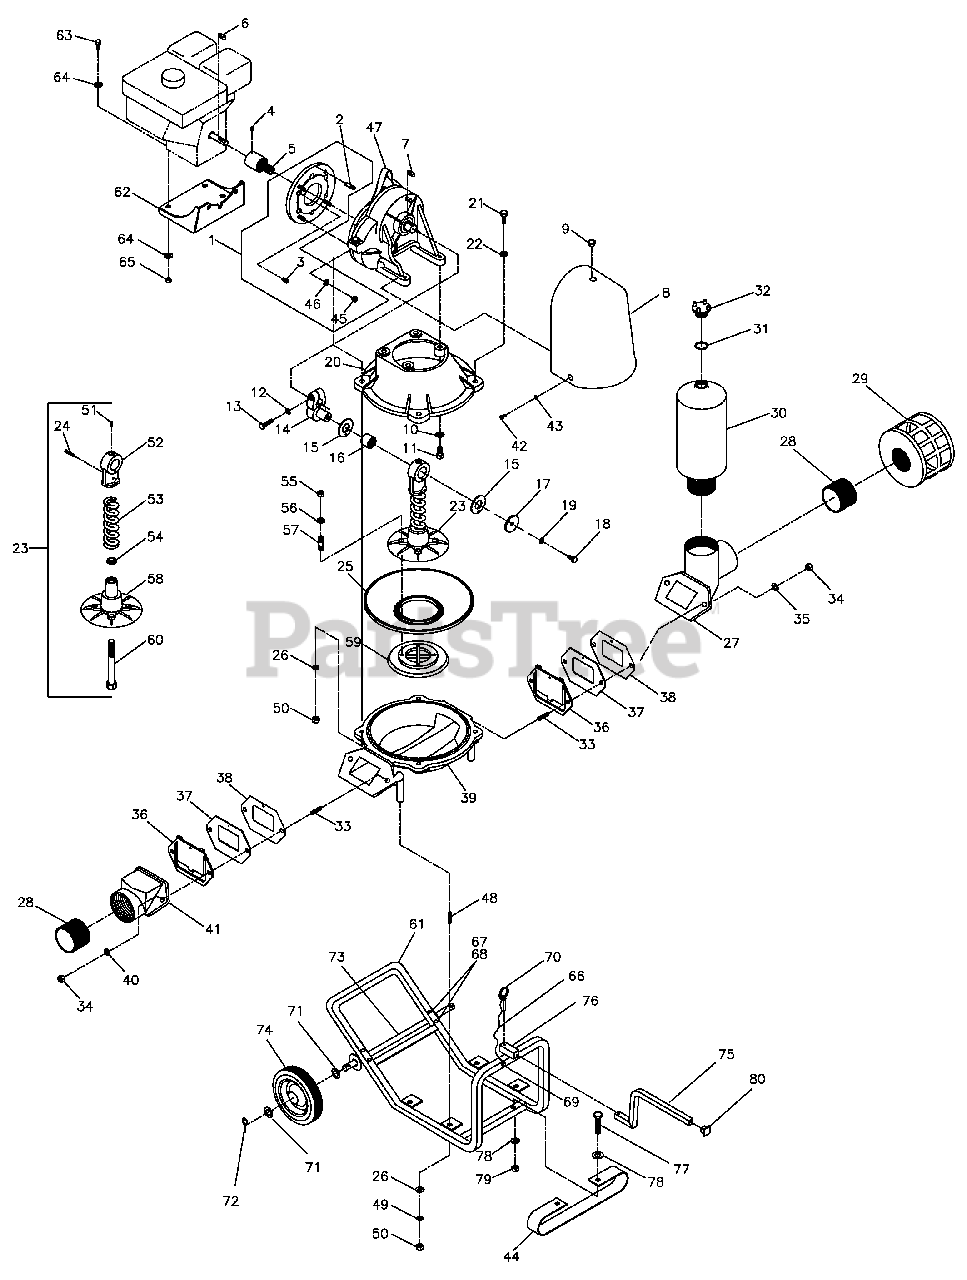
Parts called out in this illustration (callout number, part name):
1	ADAPTER, ENGINE
2	STUD (10X1.5X40) (W/NUT)
3	SCREW, ALLEN
3	SCREW, ALLEN (8X1.25X15)
4	SCREW SET (8MX1.25X10)
6	KEY STOCK (3/16X1)
8	COVER *R1* (RED)
9	PLUG, COVER (#35)
10	WASHER, PLAIN (12MM)
11	BOLT, HEX.
11	BOLT, HEX. (12X1.75X40)
12	WASHER, SPRING (10MM)
13	BOLT, HEX.
13	BOLT, HEX. (10X1.5X40)
14	CRANK (3" PUMP)
15	WASHER, FIBER
16	BEARING, CRANK
17	COVER, CONNECTING ROD BUSHING
18	BOLT, HEX.
19	WASHER, SPRING (10MM)
20	CASE, MOUNTING (UPPER) (ALUMINUM)
21	BOLT, HEX. (12X1.75X50)
22	WASHER, PLAIN (12MM)
23	ROD, CONNECTING
24	NIPPLE, GREASE
25	DIAPHRAGM, NEOPRENE
26	WASHER, FLAT (12MM)
26	WASHER, PLAIN (12MM)
27	PORT, SUCTION NPT (3")
28	NIPPLE (3")
29	STRAINER, TRASH SQ. HOLE (3")
30	CHAMBER, AIR NPT (3")
31	O-RING, AIR CHAMBER PLUG
32	PLUG, AIR CHAMBER (BRONZE)
33	STUD, FLANGE
34	NUT (12X1.75)
35	WASHER, FLAT (12MM)
35	WASHER, PLAIN (12MM)
36	CLAPPET, NEOPRENE
37	WEARPLATE, STAINLESS STEEL
38	GASKET, WEARPLATE PAPER
39	CASE (LOWER) (ALUMINUM)
40	WASHER, FLAT (12MM)
40	WASHER, PLAIN (12MM)
41	PORT, DISCHARGE (3")
42	BOLT, HEX. (8x1.25x15)
43	WASHER, FLAT (8MM)
43	WASHER, PLAIN (8MM)
44	SPRING, FRAME
45	NUT (10x1.5)
46	WASHER, SPRING (10MM)
47	TRANSMISSION, STRAIGHT TEETH (1:43)
48	STUD, PUMP CASE MOUNTING
49	WASHER, STAR (12MM)
50	NUT (12X1.75)
51	ROD END (UPPER)
53	SPRING, CONNECTING ROD
54	RING (INNER)
55	NUT (12X1.75)
56	WASHER, FLAT (12MM)
56	WASHER, PLAIN (12MM)
57	STUD (12X1.75-70)
58	ROD END (LOWER)
59	FLANGE, CONNECTING ROD
60	BOLT, SPECIAL
61	FRAME ASSY., WHEEL
62	BRACKET, ENGINE MOUNTING
63	BOLT, HEX. (5/16-18X1.5")
64	WASHER, FLAT (5/16" SAE)
65	LOCKNUT (5/16X18") (NYLOCK)
66	CABLE, KEY
67	BOLT, HEX. (5/16-18X1.5")
68	NUT, NYLOCK (5/16-18) (N/A: PURCHASE STD. HARDWARE)
69	RIVET (1/8X1/2) (N/A: PURCHASE STD. HARDWARE)
70	PIN, QUICK RELEASE
70	GRIP, QUICK RELEASE PIN-RING
71	WASHER, PLAIN (20MM)
72	PIN, SPLIT (4.0X30)
73	SHAFT, AXLE
74	WHEEL (GLEASON 10"X2.75"=254X70)
76	CLAMP, HANDLE (NOT AVAILABLE)
77	BOLT (3/8X1-3/4) (N/A: PURCHASE STD. HARDWARE)
78	WASHER (3/8") (N/A: PURCHASE STD. HARDWARE)
79	LOCKNUT, NYLOCK (3/8"-16) (N/A: PURCHASE STD. HARDWARE)
80	PLUG, HANDLE CAP
